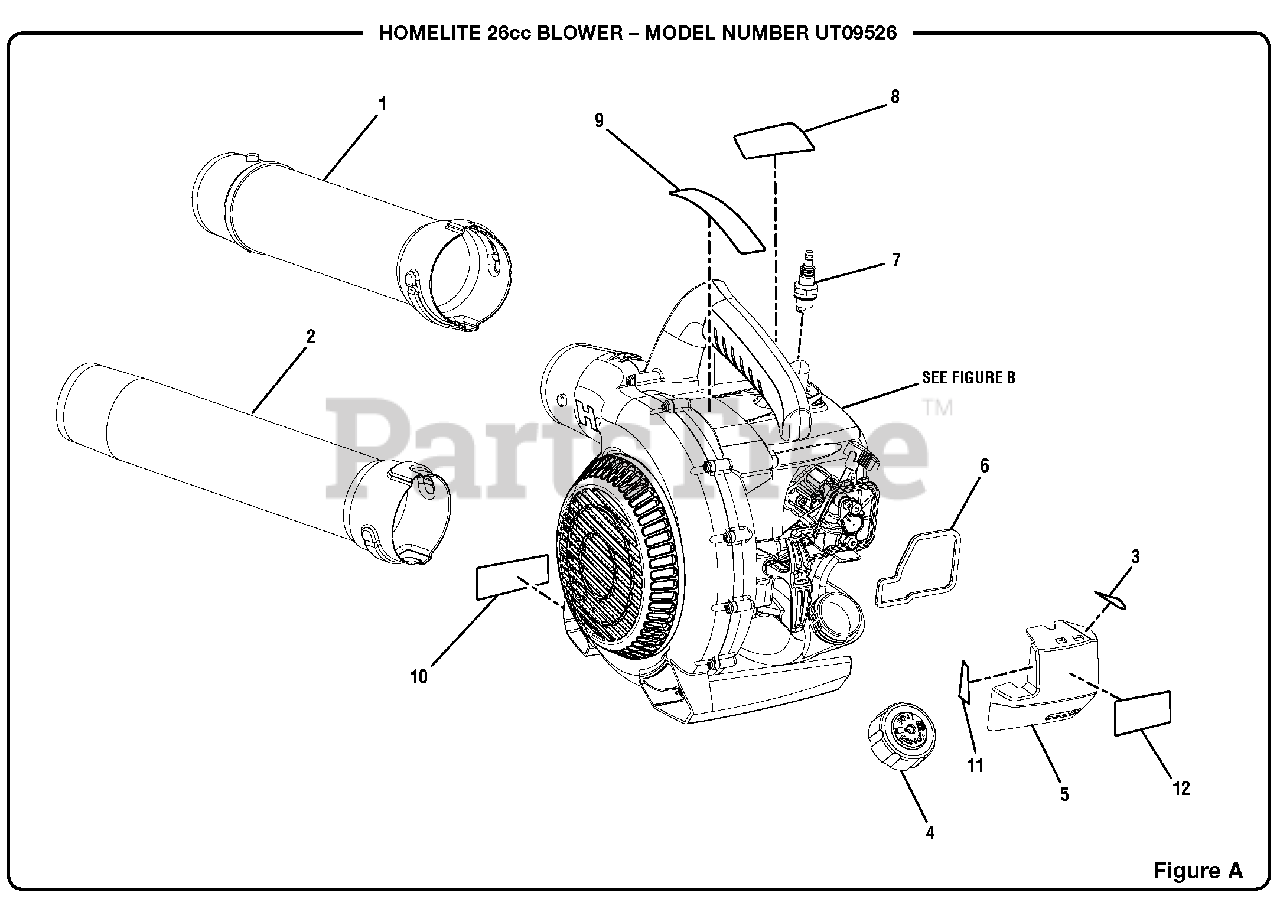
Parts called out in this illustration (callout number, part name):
1	Upper Blower Tube
2	Sweeper Nozzle
3	Throttle Label
4	Fuel Cap Assembly
5	Air Box Cover
6	Air Box Gasket
7	Spark Plug (RCJ6Y)
8	Engine Shroud Label
9	Warning Label
10	Combustion Warning Label
11	Choke Label
12	Starting Instructions Label
